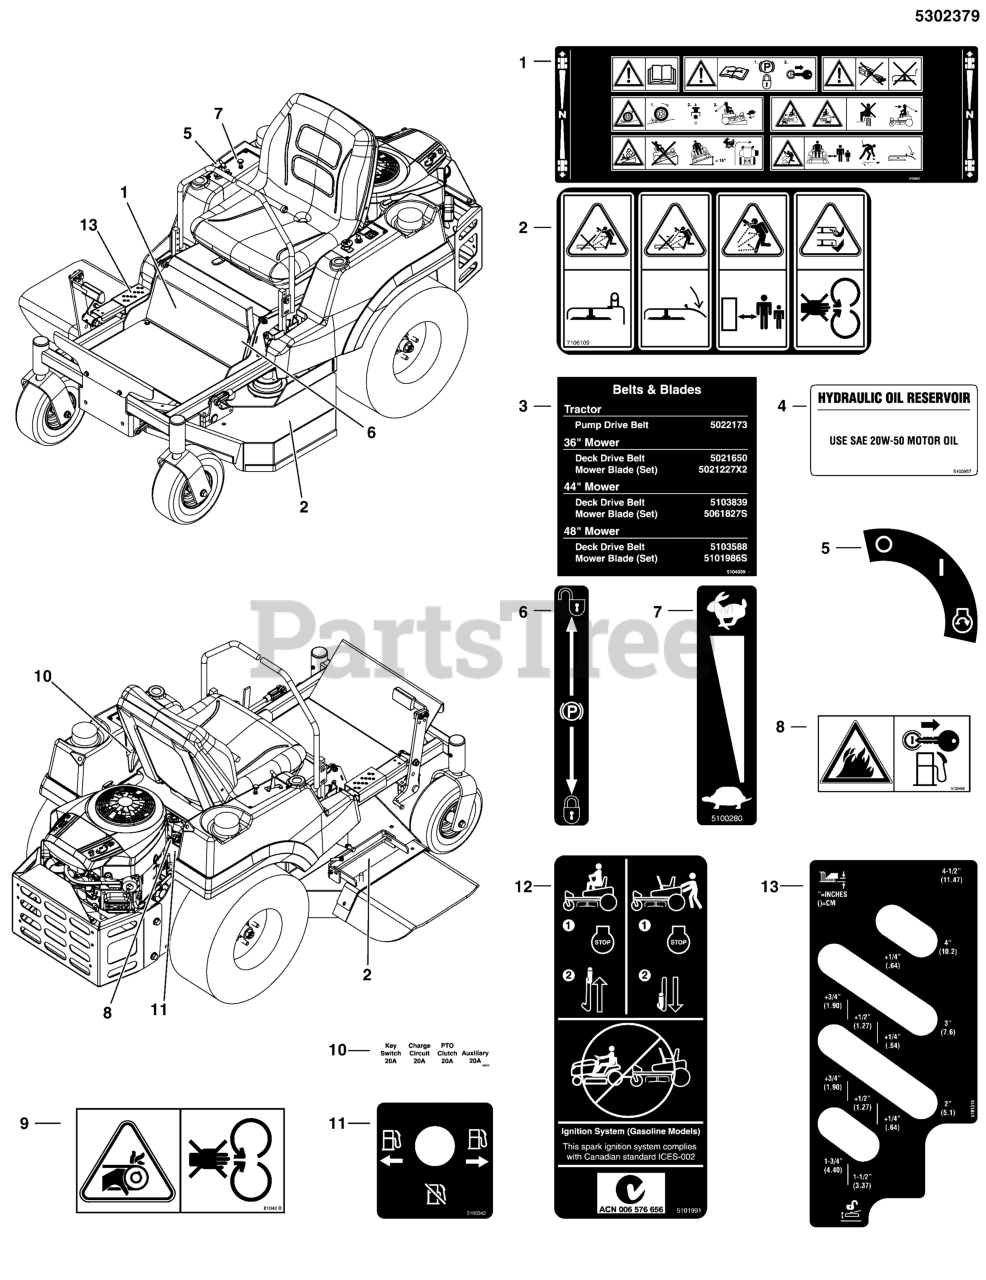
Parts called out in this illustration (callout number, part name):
1	DECAL, MAIN SAFETY, ANSI CE
2	DECAL, DISCHARGE SAFETY, EXPORT
3	DECAL, BELT & BLADE, F50XT, 36, 44, 48
4	DECAL, HYDRAULIC OIL, SAE 20W50
5	DECAL, IGNITION SWITCH
6	DECAL, PARKING BRAKE SYMBOLS
7	DECAL, THROTTLE CONTROL
8	DECAL, FIRE ANSI EXPORT
9	DECAL, CE DANGER
10	DECAL, FUSE LOCATION
11	DECAL, FUEL VALVE
12	DECAL, TRANSAXLE RELEASE
13	DECAL, CUT HEIGHT, S50X
